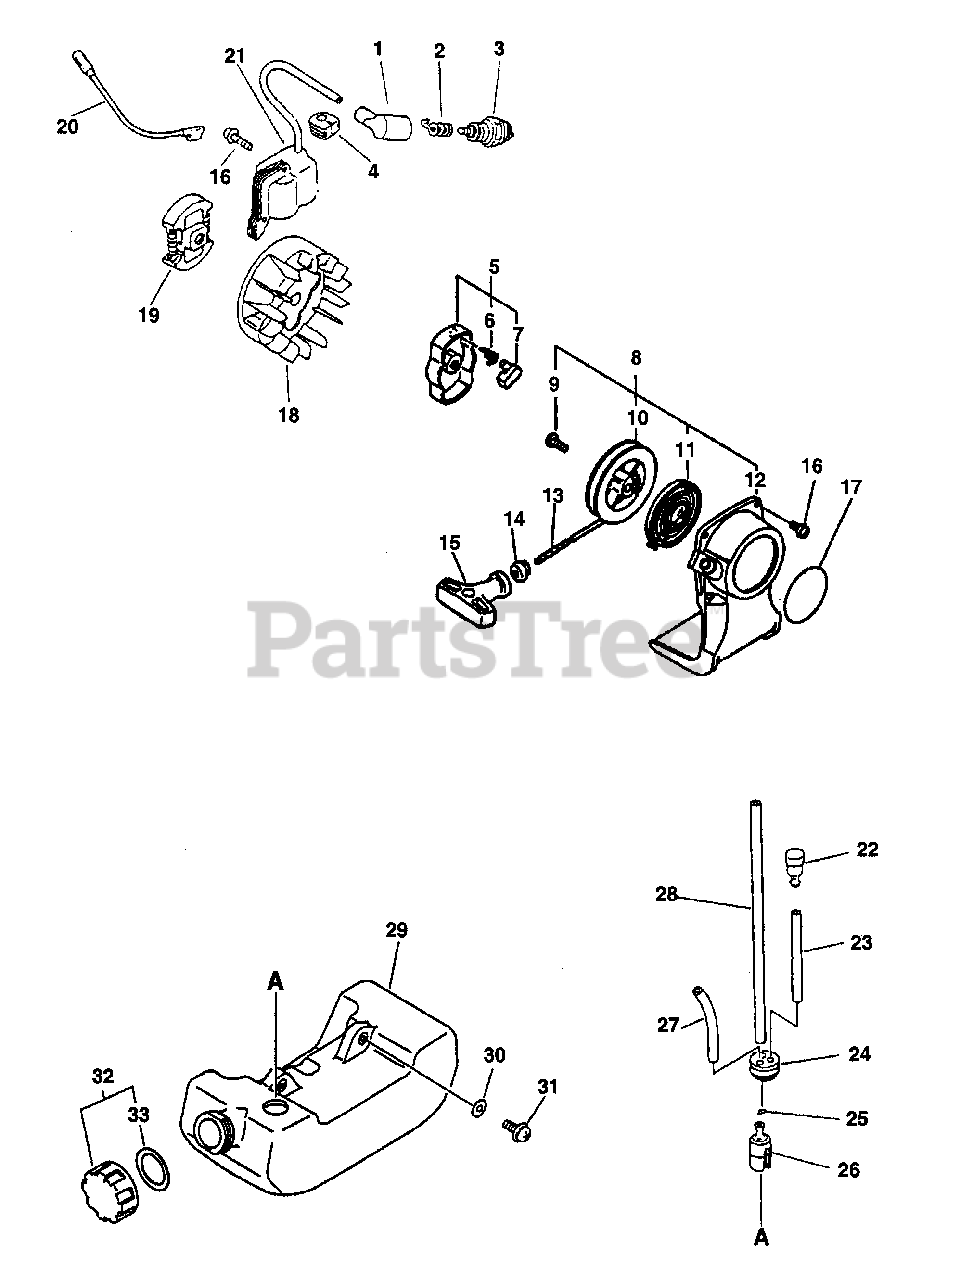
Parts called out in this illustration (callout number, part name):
1	CAP, SPARK PLUG
2	TERMINAL, SPARK PLUG
3	SPARK PLUG - BPM7A
3	SPARK PLUG - BPMR7A
5	PAWL ASSY, STARTER
6	SPRING, RETURN
7	PAWL, STARTER - BLACK
8	STARTER ASSY
9	SCREW
10	REEL, ROPE
11	SPRING, RECOIL
12	CASE, RECOIL STARTER
13	ROPE, STARTER
14	GUIDE, ROPE
15	GRIP, STARTER
16	SCREW 4×22
17	LABEL, ECHO
18	FLYWHEEL
19	CLUTCH ASSY
20	LEAD - GROUND
21	COIL, IGNITION
22	VENT ASSY
23	PIPE K43B3×5×70
24	GROMMET, FUEL Ø5
25	CLIP 6 MM
26	FILTER, FUEL
27	PIPE, FUEL RETURN 3×6×90 MM CLEAR
28	PIPE, FUEL
29	TANK, FUEL
30	WASHER 5.5×12×0.8
31	SCREW 5×16
32	CAP ASSY, FUEL
33	GASKET, FUEL CAP
